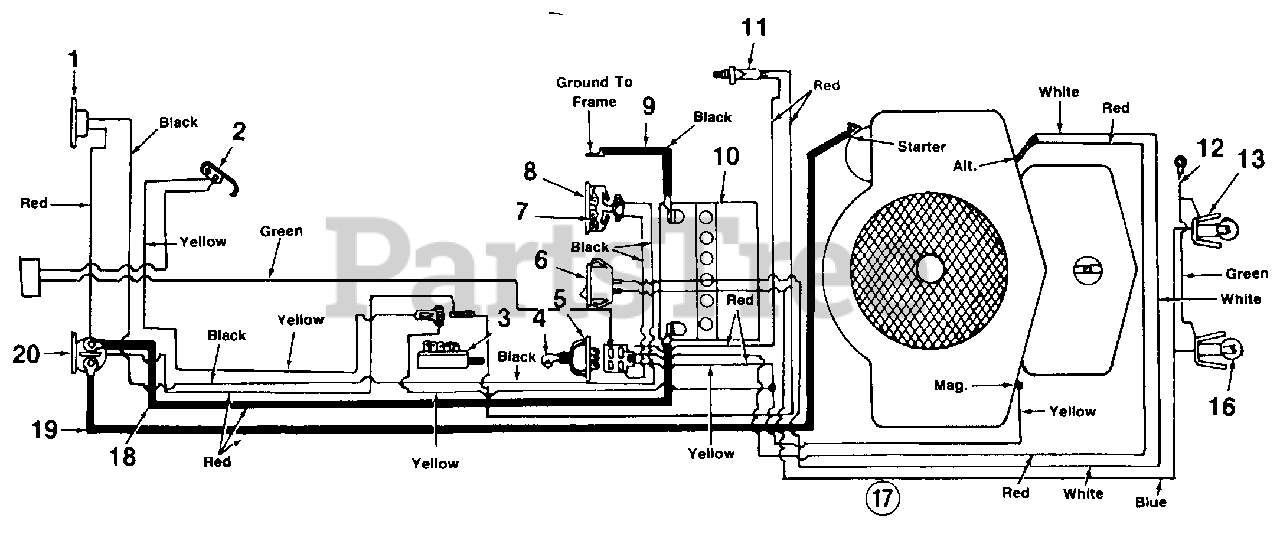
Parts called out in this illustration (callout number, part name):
1	Circuit Breaker
2	Spring Switch
3	Safety Switch Dpst.
4	Ignition Key
5	Ignition Switch
6	Headlight Switch
7	Foam Strip
8	Ammeter
9	Ground Wire 14.0" Lg.
10	12 Volt Battery
11	Safety Switch
12	Ground Wire
13	Socket
16	Lamp
17	Wire Harness
18	Electric Wire 27.0" Lg.
19	Electric Wire 32.5" Lg.
20	Solenoid
